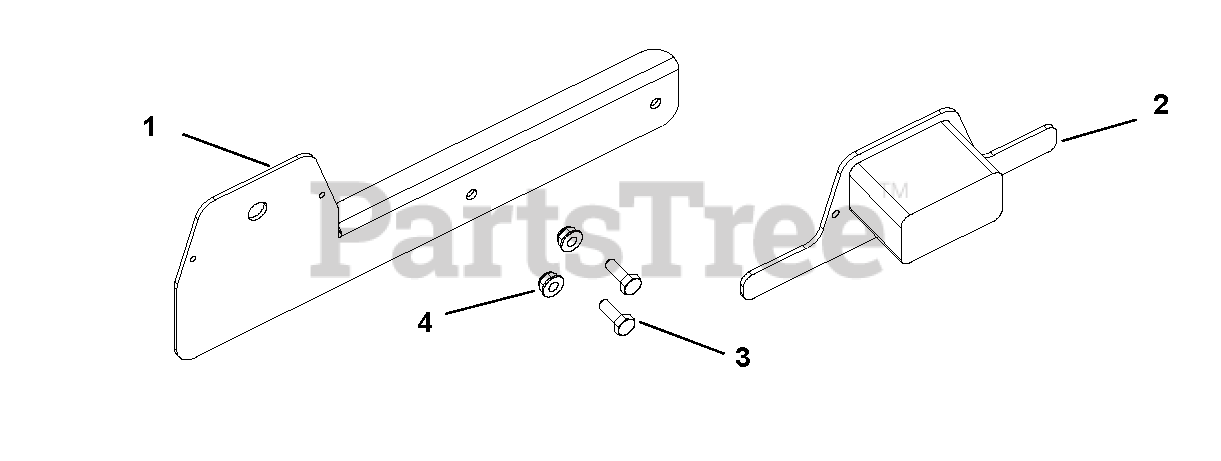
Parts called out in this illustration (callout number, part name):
1	Bracket, License Plate (Ships preassembled with item 2)
2	Light (Ships preassembled with item 1)
3	Bolt, Hex .25-20 x .75
4	Nut, Nyloc Flange .25-20
